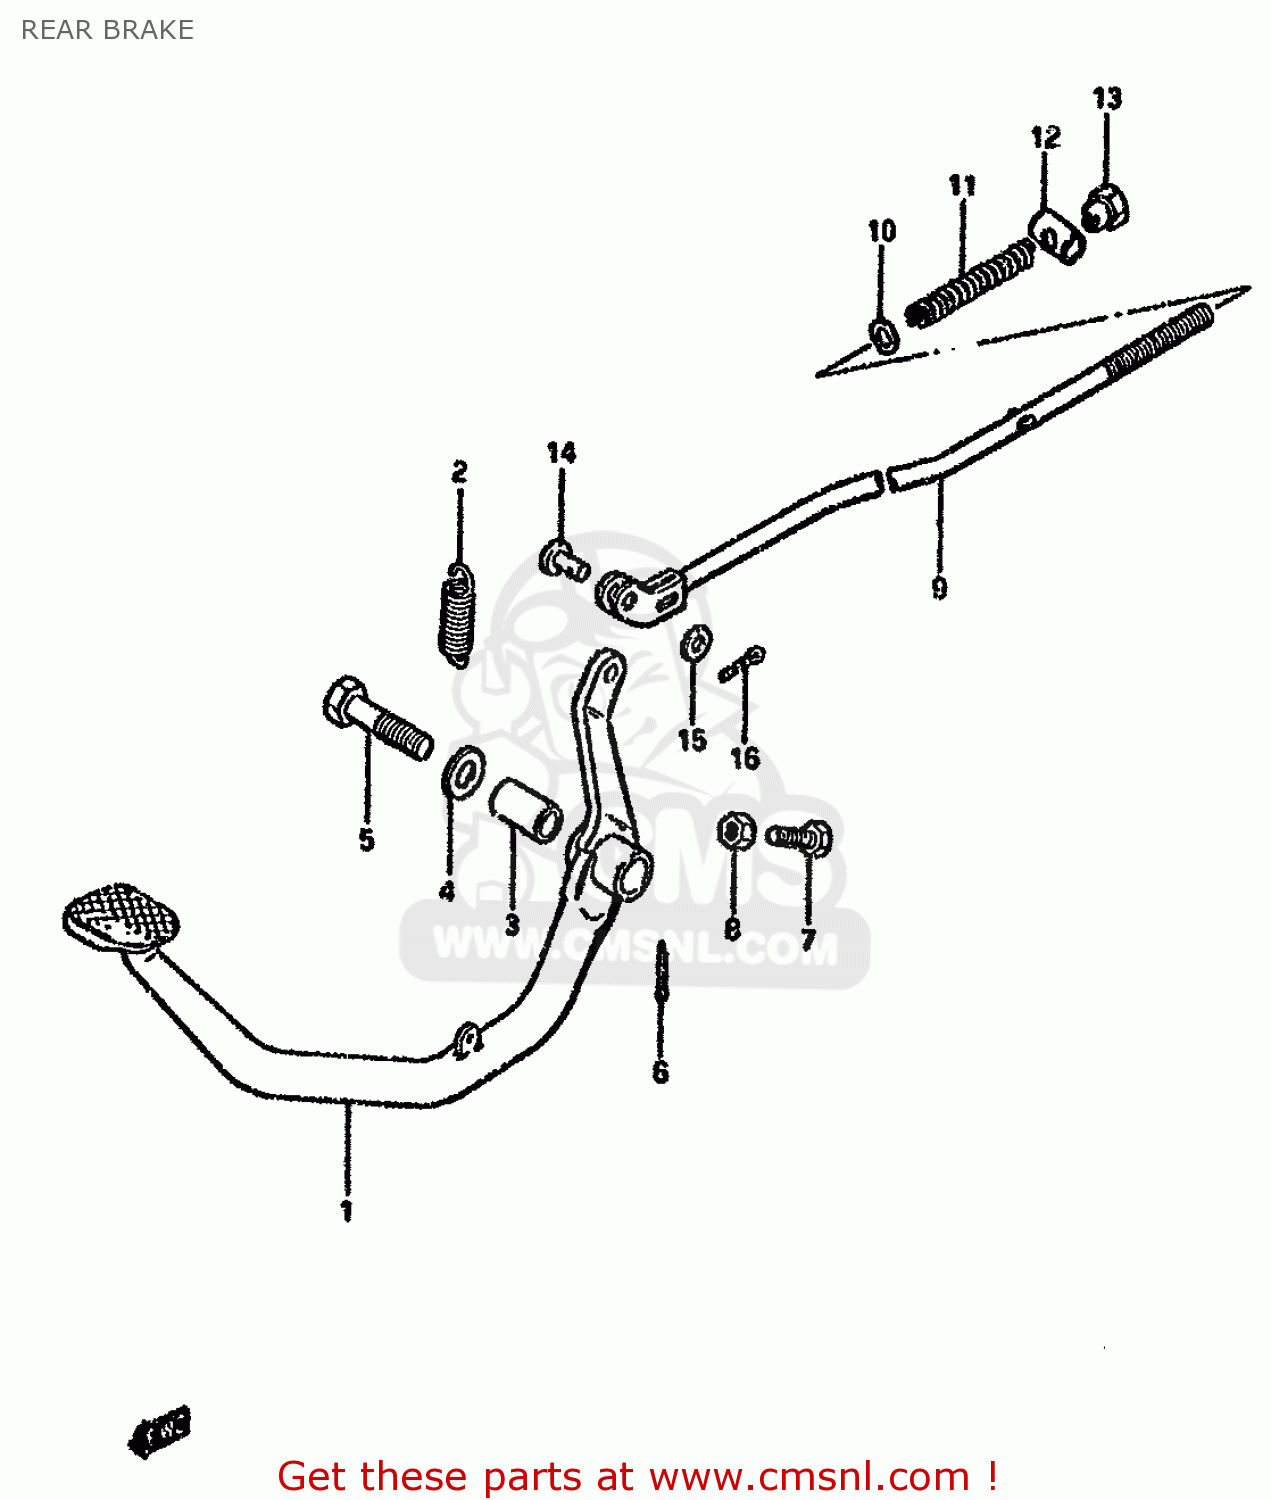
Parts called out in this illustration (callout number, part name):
1	PEDAL,BRAKE
2	SPRING
3	SPACER,BRAKE PEDAL BOSS
4	WASHER
5	BOLT 10X52
6	PIN 20X20
7	BOLT(6X23)
8	NUT 6MM
9	ROD ASSY,RR BRAKE
10	WASHER
11	SPRING
12	PIN(11X18)
13	NUT
14	PIN(L:13.5)
15	WASHER
16	PIN 20X20
